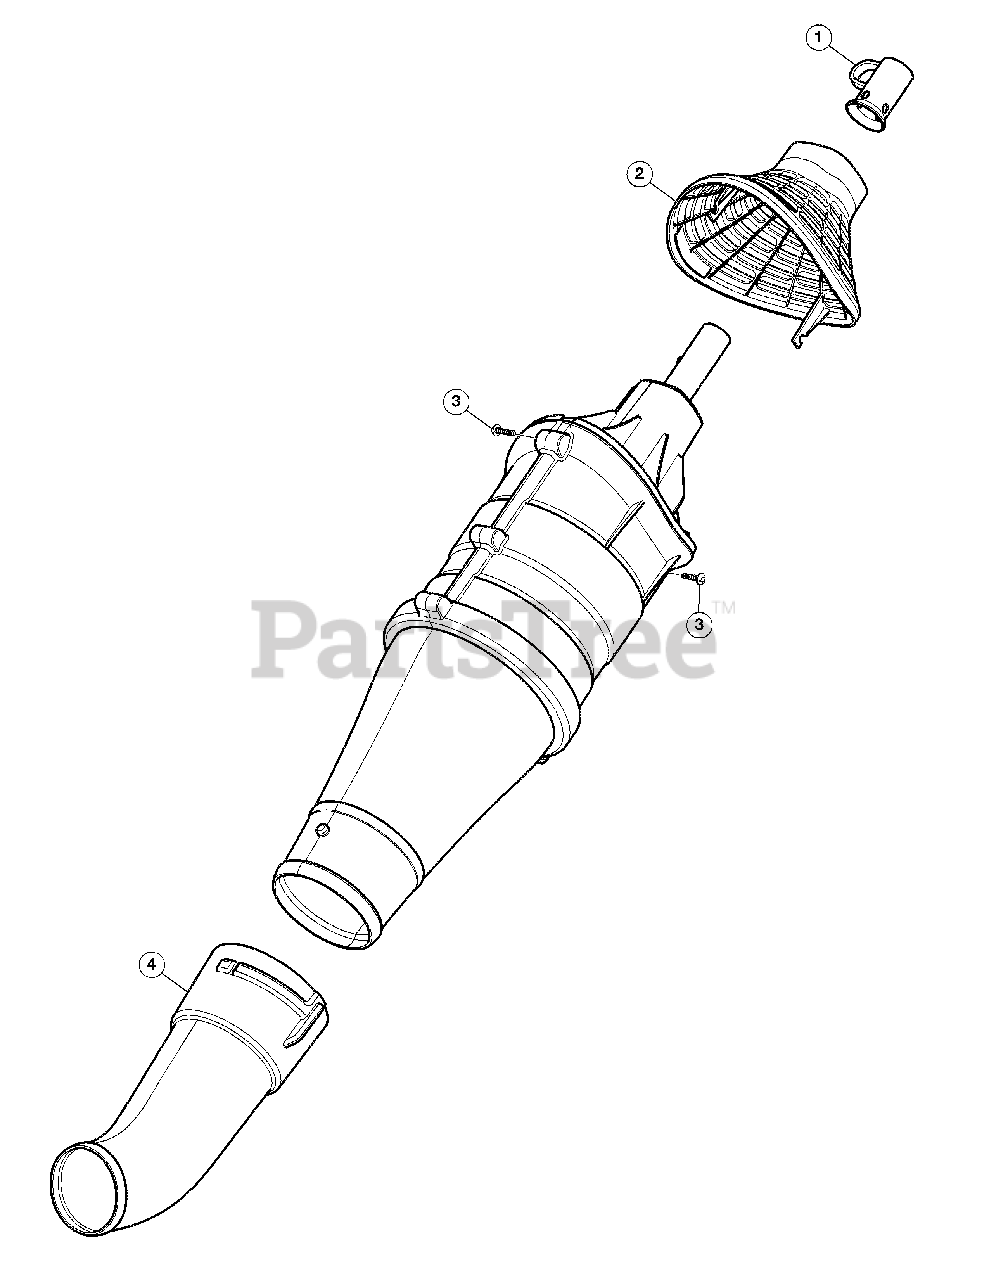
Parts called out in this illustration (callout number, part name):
1	Hanger
2	Blower Intake Housing
4	Blower Nozzle
